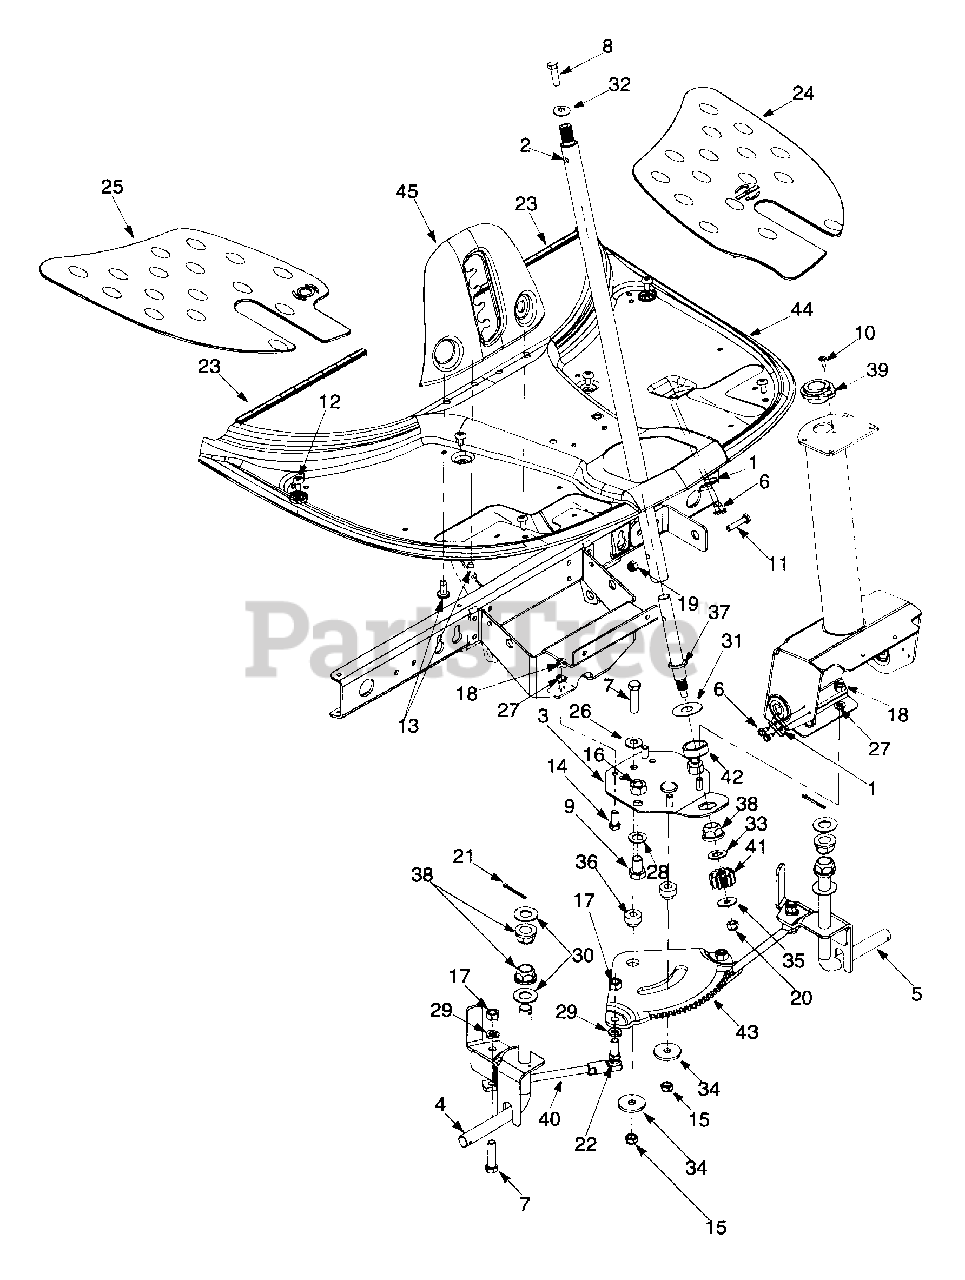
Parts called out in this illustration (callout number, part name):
1	Switch Plate
4	Front Axle Assembly: RH
5	Front Axle Assembly: LH
6	Hex Screw AB
7	Hex Screw 3/8-24 x 1 5" Gr 5
8	Lock Screw 5/16-18 x 1.0" Gr.5
9	Hex Screw 1/2-13 x 0.75"
10	Oval Csunk Screw #10-16 x 0.625"
11	Hex Screw 1/4-20 x 1.25 Gr.5
12	AB Screw 1/4-14 x 0 625"
13	Self-Tapping Screw 5/16-18 x 0.75"
14	Hex Screw 5/16-18 x 0.75"
15	Lock Nut 3/8-24
16	Hex Nut 1/2-13
17	Hex Nut
18	Hex Nut
19	Lock Nut 1/4-20
20	Lock Nut
21	Cotter Pin
22	Ball Joint
23	Trim Strip
24	Floor Pad LH
25	Floor Pad RH
26	Bell Washer
27	Lock Washer
28	Flat Washer
29	Lock Washer
30	Flat Washer
31	Flat Washer
32	Belleville Washer
33	Flat Washer
34	Flat Washer
35	Flat Washer
36	Spacer
37	Steering Adapter
38	Hex Flange Bearing
39	Bearing Steering Column
40	Tie Rod
41	Pinion Gear
42	Spacer
43	Gear Steering Segment
